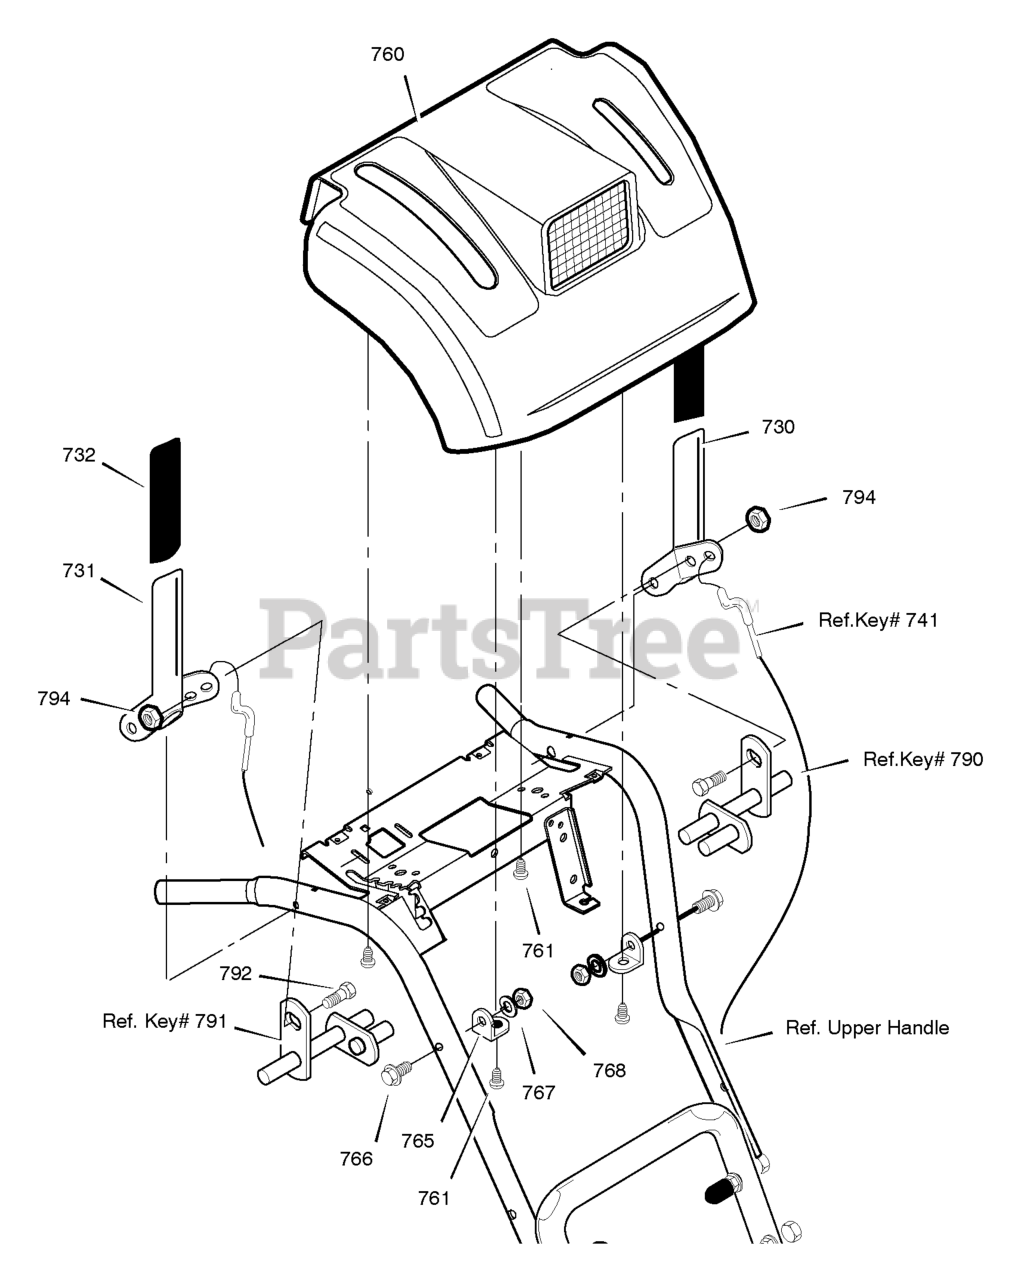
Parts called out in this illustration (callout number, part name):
730	CLUTCH HANDLE LH
731	CLUTCH HANDLE RH
732	GRIP, CLUTCH LEVER
760	PANEL, CONTROL
765	BRACKET, PANEL
766	SCREW, 5/16-18 x 1.75
767	WASHER
768	NUT, 5/16-18
792	BOLT, 1/4-20 X 0.50
794	NUT, 1/4-20
